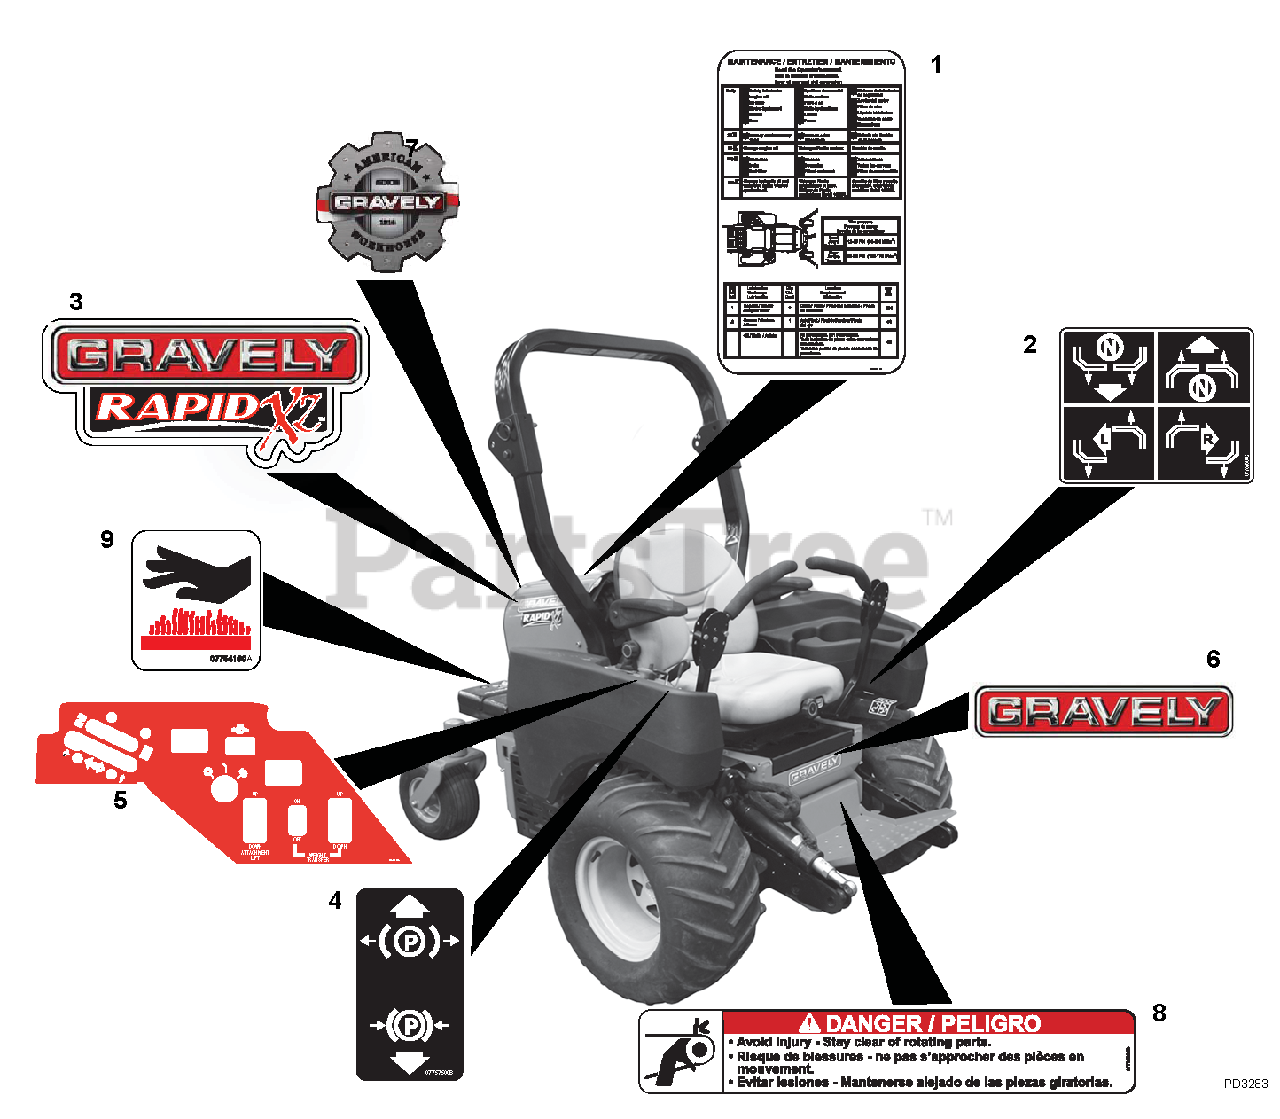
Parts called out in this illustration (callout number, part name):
1	DECAL, SERVICE INSTR. RAPID XZ
2	DECAL, INSTRUCTIONAL-STEERING
3	DECAL, GRAVELY RAPID XZ HOOD
4	DECAL, PARKING BRAKE LEVER
5	DECAL, CONTROL PANEL RAPID XZ
6	Decal, 9.5" Gravely Logo
7	DECAL, AMERICAN FLAG
8	DECAL- DANGER
9	DECAL, HOT SURFACE
